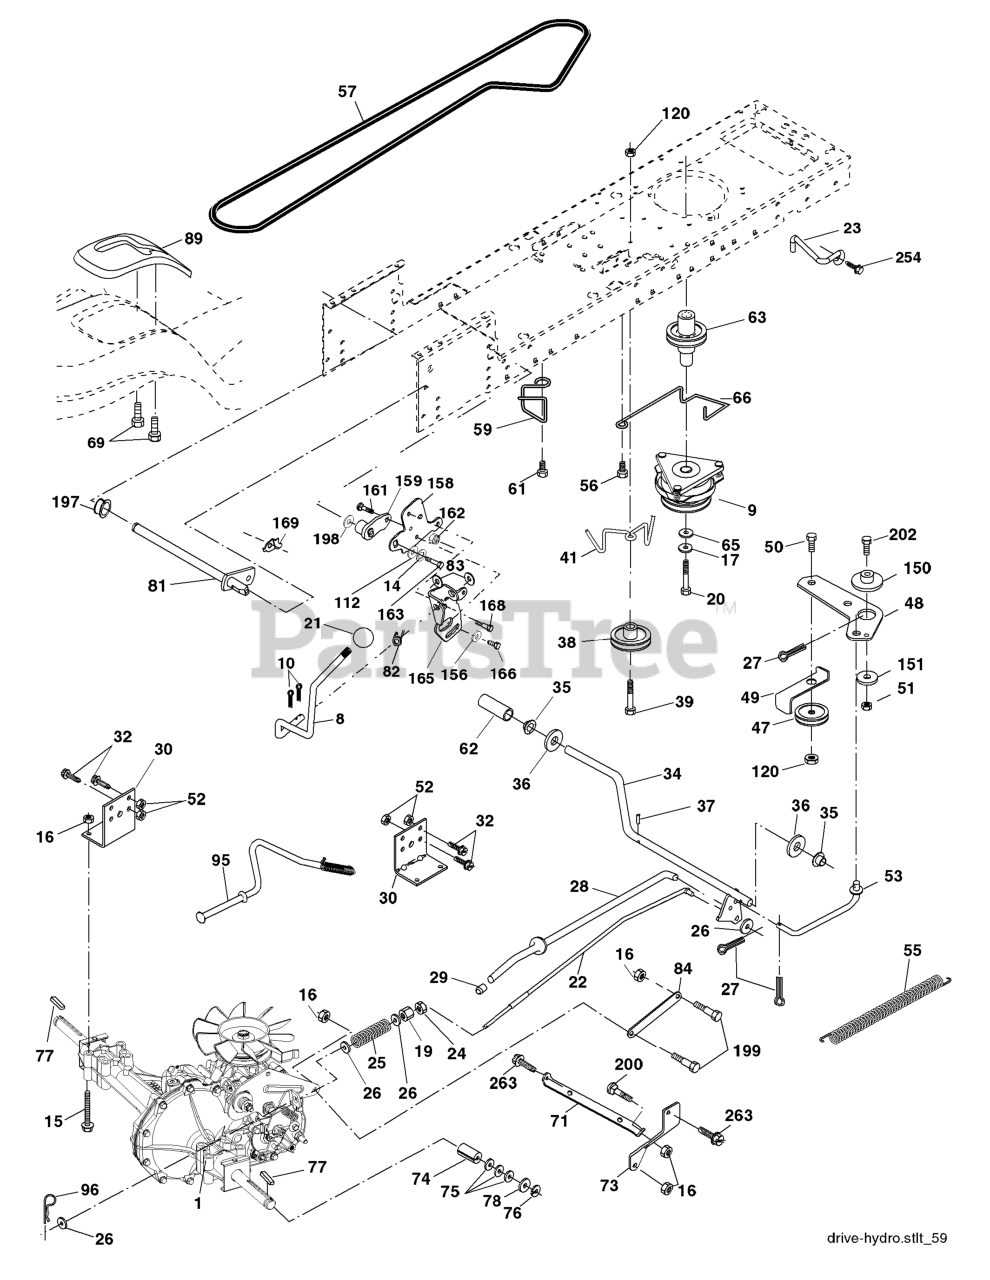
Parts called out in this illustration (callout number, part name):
8	ROD SHIFT FENDER ADJUST STLT
9	CLUTCH ELECTRIC
10	PIN COTTER
14	LOCKWASHER
15	BOLT HEX 5/16-18 GR 5
16	NUT.71038.31-18.HEX.NYLOCK
19	NUT
20	BOLT HEX 7/16-20X4-1/4"
21	KNOB.DELUXE.(PISTOL.GRIP).BLAC
22	ROD BRAKE HYDRO
23	BRACKET, ANTI-ROTATION
24	NUT
25	SPRING ROD LT
26	WASHER
27	COTTER PIN
28	ROD, PARKING BRAKE
29	PLUNGER CAP
30	BRKT, TRNSXLE MNT 20"
32	BOLT
34	SHAFT, FOOT PEDAL
35	BEARING.NYLON
36	WASHER LT
37	DRIVE PIN
38	PULLEY IDLER COMPOSITE
41	KEEPER, BELT IDLER
47	IDLER PULLEY
48	BELLCRANK, CLUTCH
49	RETAIN BELT
50	BOLT.3/8-16X1.50
52	LOCKNUT
53	LINK, CLUTCH LT
55	SPRING, RETURN LT
56	SCREW.3/8-16
57	DRIVE BELT, LTH & YTH TRACTORS
59	KEEPER, BELT CENTER
61	SCREW 3/8-16X.875
62	PEDAL COVER T
63	PULLEY- ENGINE
65	LOCKWASHER
66	KEEPER BELT ENGINE
69	SCREW.HI-LO.CONSOLE
71	STRAP TORQUE LH HYDRO
73	STRAP TORQUE RH HYDRO
74	SPACER AXLE
77	SQUARE KEY
81	SHAFT ASM CROSS TAPERED
82	SHIFT SPRING
83	WASHER
84	LINK TRANSAXLE
89	CONSOLE SHIFT STL AUTO
95	CONTROL ASM. BYPASS HYDRO
96	RETAINER M
112	WASHER LT
120	NUT LOCK FLG 3/8-16 UNC
150	SPACER, RETAINER
151	WASHER 12/32X2X10GA
156	WASHER.SRRTD.5/16
158	BRACKET
159	RB HUB.SHIFT
161	BOLT
162	NUT.CROWNLOCK.1/4
163	BOLT
165	RP BRACKET
166	CAPSCREW.HXHD.FLG.5/16-18X.625
168	BOLT.SHOULDER.5/16-18X
169	PLATE.FASTENING.CROSS.SHAFT
197	NYLINER SNAP 5/8" ID
198	WASHER.NYL.7/8IDX.105"HYD CR
199	BOLT SHOULDER 5/16-18 UNC
200	BOLT
254	SCREW 3/8-16X1
263	SCREW, 3/8-16X3/4
